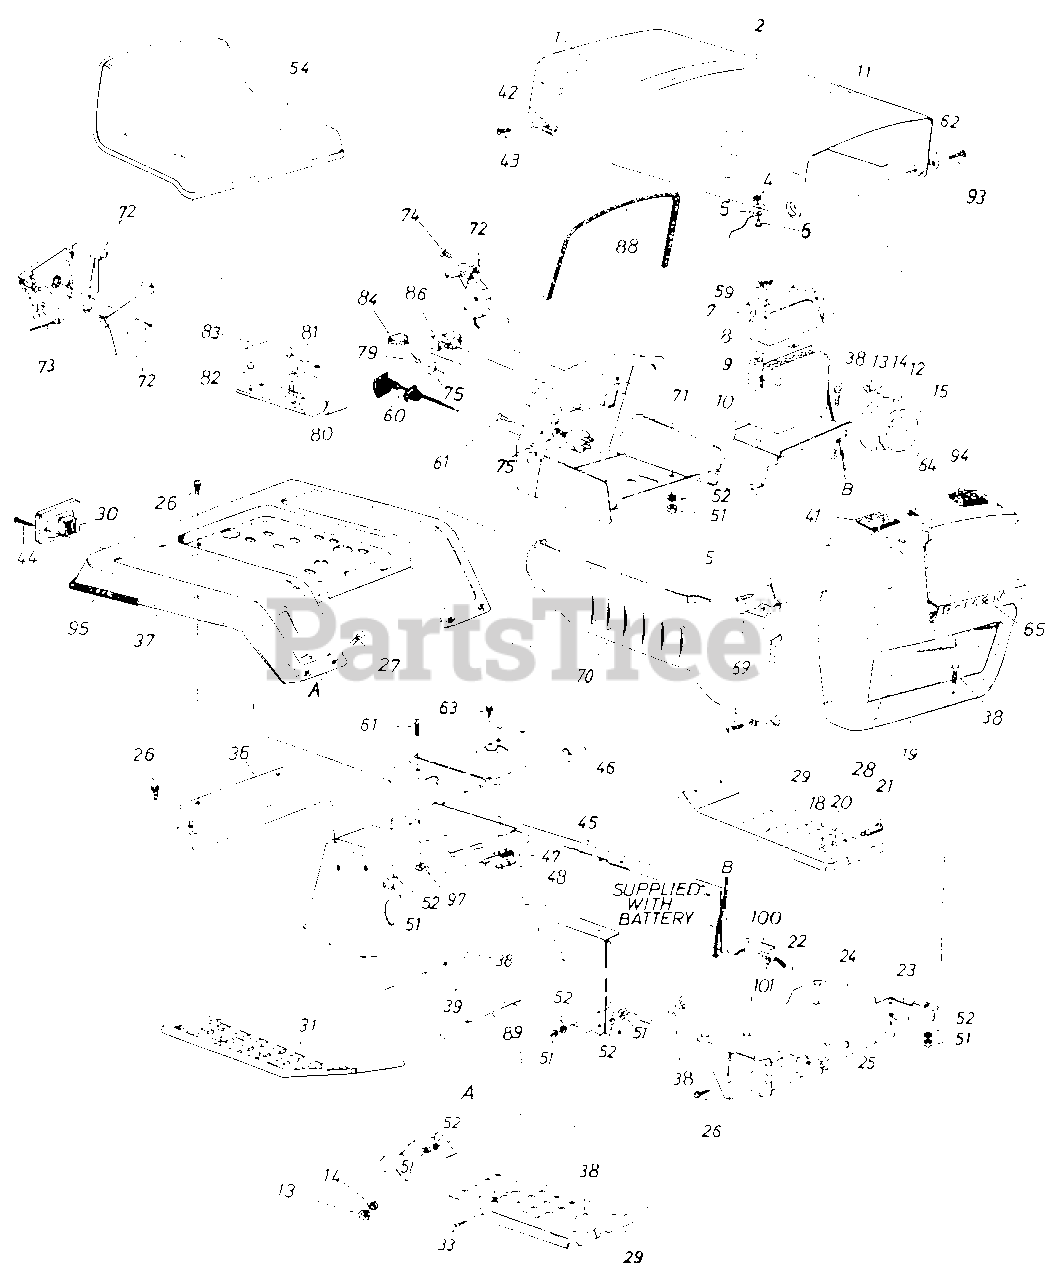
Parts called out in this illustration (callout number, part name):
1	Hood Spring
5	Hood Stop 7" Lg.
6	Pop Rivet .188" Dia.
7	Battery Cover
8	12 Volt Battery
9	Battery Hold Down Rod
10	Battery Bracket
11	PVC Foam Strip
12	Headlight Retainer
13	Hex Nut 1/4-20 Thd.
14	L-Wash 1/4 " I.D.
15	Headlight
18	Hex Nut 3/8-16 Thd.
21	Shld. Bolt .50" Dia. x .84
22	Lower Frame
23	Grille Mount Brkt. L.H.
24	Front Pivot Brkt.
25	Grille Mount Brkt. R.H.
26	Hex Wash. Hd. AB-Tap Scr. 5/16 x .75" Lg.
27	Carriage Bolt 1/4-20 x .50" Lg.
28	Grille Insert
29	Running Board
30	Taillight
31	Foot Pad
33	Truss Mach. Scr. 5/16-18 x .75" Lg.
36	Fender Mount Brace
37	Fender
38	Hex Bolt 5/16-18 x .75" Lg.
39	R.H. Side Frame
41	Foam Strip
42	Hood Spring Retainer
43	Self-Tap Scr. .5" Lg.
44	Truss AB-Tap Scr. #6 x .62" Lg.
45	1 L.H. Side Frame
46	Shift Cover
47	Reverse Safety Switch
48	Insulator Nut Plate
51	Hex Nut 5/16-18 Thd.
52	L-Wash. 5/16" I.D.
54	Seat Ass'y.
59	Wing Nut 1/4-20 Thd. Plastic
60	Choke Control 46" Lg.
61	Truss Mach. Tap Scr. #10 x .50" Lg.
62	Washer .39" I.D. x .62" O.D.
63	Hex Wash. Hd. AB-Tap Scr. #8 x .50
64	Self-Tap Scr. #8 x .5" Lg.
65	Bezel
69	Truss Hd. Scr. 1/4-20 x .75" Lg.
70	R.H. Grille Side Panel
71	Dash Panel Ass y.
72	Throttle Control Box Ass'y.
73	Throttle Control Wire 35"
74	Truss Mach. AB-Tap Scr. #10 x .5" Lg.
75	Ignition Switch
79	Ignition Key
80	Hex Bolt 1/2-13 x 1.00" Lg. (Grade 5)
81	L-Wash. 1/2" I.D.
82	Hex Bolt 5/16-18 x 1.00" Lg.
83	Seat Spring 5.5" High
84	Light Switch
86	Ammeter
88	Molding Strip 27" Lg.
89	Running Board Rod
93	Shld. Bolt .375 Dia. x .125
94	L-Nut 1/4-28 Thd.
95	Trim Strip 31.0" Lg.
97	Speed Nut #10Z
100	Brake Cable Bracket
101	Cable Tie
